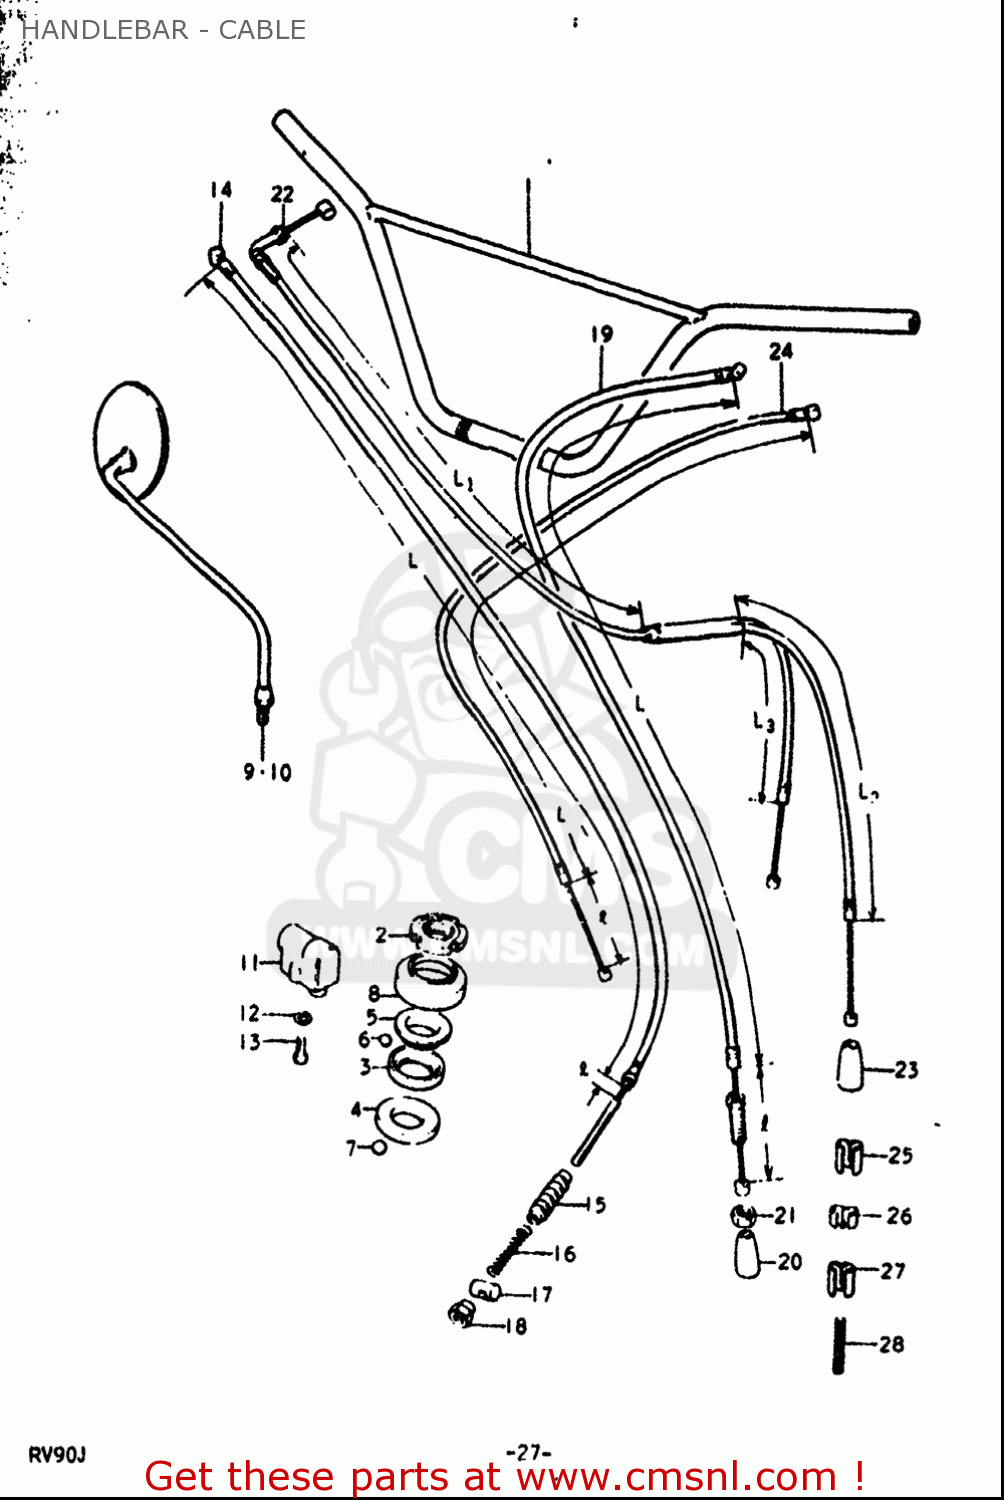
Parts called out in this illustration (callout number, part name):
1	HANDLEBAR
2	NUT,STEERING STEM(25X44X10)
3	RACE,STEERING INNER UPR
4	LACE,STEERING INNER LWR
5	RACE,STEERING OUTER UPR
6	BALL
7	BALL
9	MIRROR ASSY,RR VIEW,R
10	MIRROR ASSY,RR VIEW,L
11	LOCK ASSY,STEERING
12	WASHER,LOCK
13	SCREW
14	CABLE ASSY,FR BRAKE(L:1175)
15	SEAL,DUST(7X16X75)
16	SPRING
17	BRAKE ROD LEVER
18	BRAKE ROD ADJ N
19	CABLE ASSY,CLUTCH
20	SEAL,DUST(7X18X30)
21	NUT
22	CABLE ASSY,THROTTLE
23	SEAL,DUST(7X18X30)
24	CABLE,STARTER
25	CLIP
26	CLIP
28	PROTECTOR,CABLE
